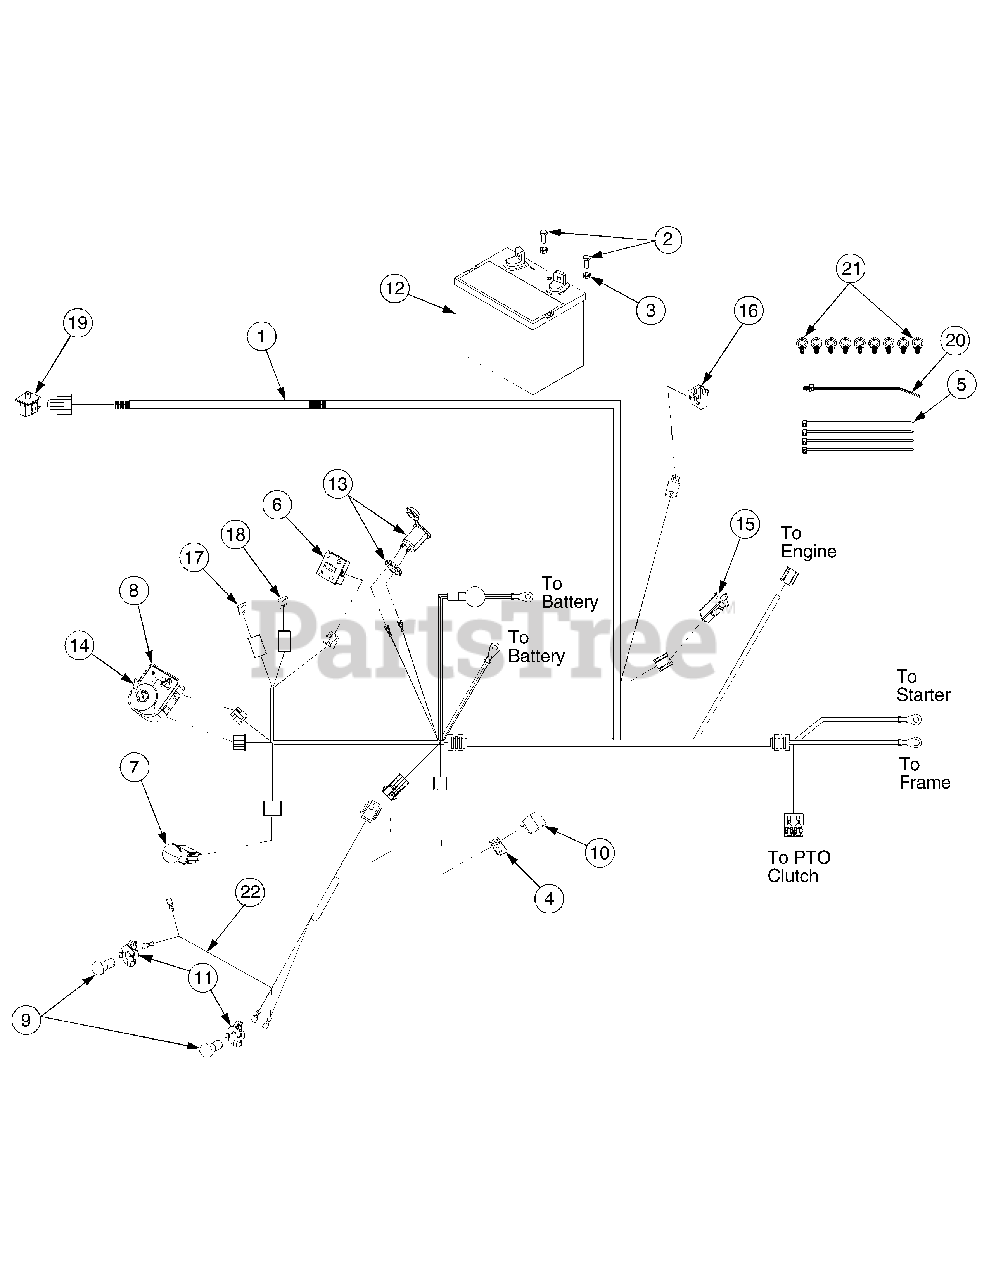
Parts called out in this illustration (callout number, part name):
1	Wire Harness, Main
2	Screw, Hex, 1/4-20 x .75 GR5
4	Gasket, Silicone
5	Tie, Self-Clinch Cable
6	Meter, Indicator / Hour
7	Switch, PTO
8	Switch, Key/Module
9	Lamp, Head Light
10	Relay
11	Socket, Light, 1/4 Turn
13	Receptacle, Power 12V
14	Key, Ignition
15	Switch, Interlock (Brake)
16	Switch, Snap Mount (Reverse)
17	Fuse, 25 Amp
18	Fuse, 5 Amp
19	Switch, Seat
20	Tie, Pushmount
21	Clip, Cable
22	Harness, Head Light
